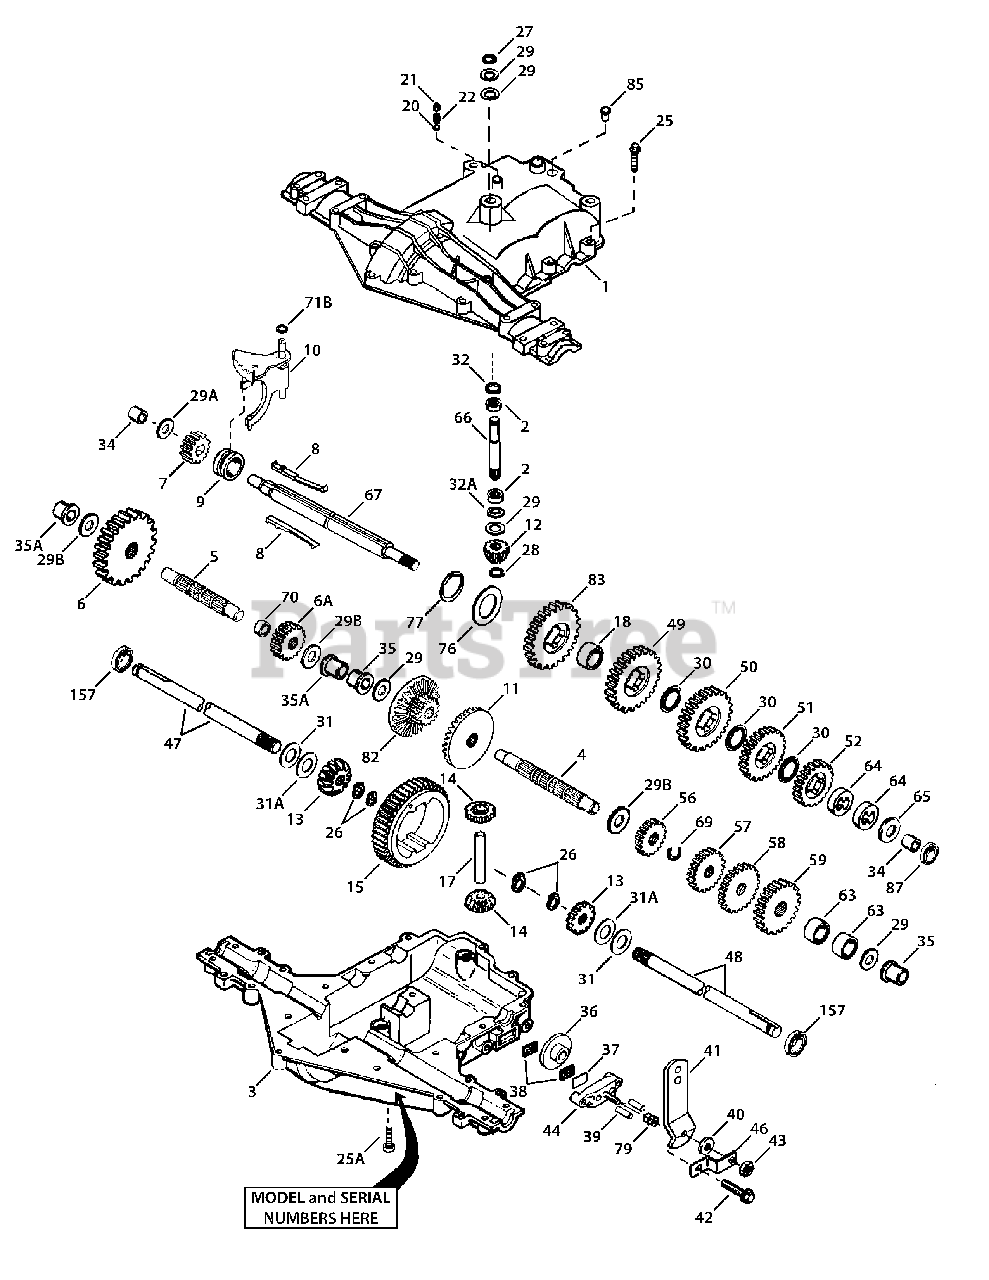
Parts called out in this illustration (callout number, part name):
1	Transaxle Cover
2	Needle Bearing (1/2" long)
3	Transaxle Case
4	Countershaft
5	Output Shaft
6	Spur Gear (38T-PM/SER)
6A	Spur Gear (15T-PM/SER)
7	Spur Gear (11T-PM/SER)
8	Shift Key Set (Qty. 2)
9	Shift Collar
10	Shift Rod & Fork Assembly
11	Bevel Gear (30T-PM)
12	Input Bevel Pinion (13T-PM)
13	Bevel Gear 13T (Incl. ref. 13 & 14)
14	Bevel Gear 13T (Incl. ref. 13 & 14)
15	Ring Gear (43T)
18	Spacer (1.130" x .695")
20	Ball (Stainless Steel 5/16" dia.)
21	Screw, 3/8-16 x 3/8"
25	Screw, 1/4-20 x 1-1/4"
25A	Screw, 1/4-20 x 1-3/8"
26	Retaining Ring
27	Retaining Ring
28	Retaining Ring
29	Washer .627" ID .031"
29A	Thrust Washer (.563" ID x .031")
29B	Thrust Washer (.762" ID X .031")
30	Shift Washer (Cupped)
31	Washer .750" ID .56"
31A	Washer .750" ID .062
32	Oil Seal 5/8"
32A	O Ring (.823" OD)
34	Bushing (.563")
35	Flanged Bushing (.625" ID)
35A	Flanged Bushing (.751" ID)
36	Brake Disk
37	Brake Pad Plate
38	Brake Pad (pkg. of 2)
39	Dowel Pin .3125" x .750"
40	Washer .312" ID .059"
41	Brake Lever
42	Screw 1/4-20 x 1-3/8"
43	Lock Nut 5/16-24
44	Brake Pad Holder
47	Axle (10.719" long) (Incl. 26)
48	Axle (15.312" long) (Incl. 26)
49	Spur Gear (27T-PM/IC)
50	Spur Gear (22T-PM/IC)
51	Spur Gear (19T-PM/IC)
52	Spur Gear (16T-PM/IC)
56	Spur Gear (13T-PM/SER)
57	Spur Gear (18T-PM/SER)
58	Spur Gear (21T-PM/SER)
59	Spur Gear (24T-PM/SER)
63	Countershaft Spacer 1-1/8" x 3/8’’
64	Brake Shaft Spacer 1-3/8" x 3/8’’
65	Washer .563" ID .062
66	Input Shaft
67	Brake Shaft
69	Retaining Ring (.75" x .042")
70	Spacer (.890")
76	Flat Washer (1.128" ID x .058")
77	Retaining Ring (1.125" x .050")
82	Bevel (30T) & Spur Gear
83	Spur Gear (27T-PM/IC)
85	Oil Fill Plug
87	Oil Seal 9/16" ID
157	Oil Seal3/4" ID
